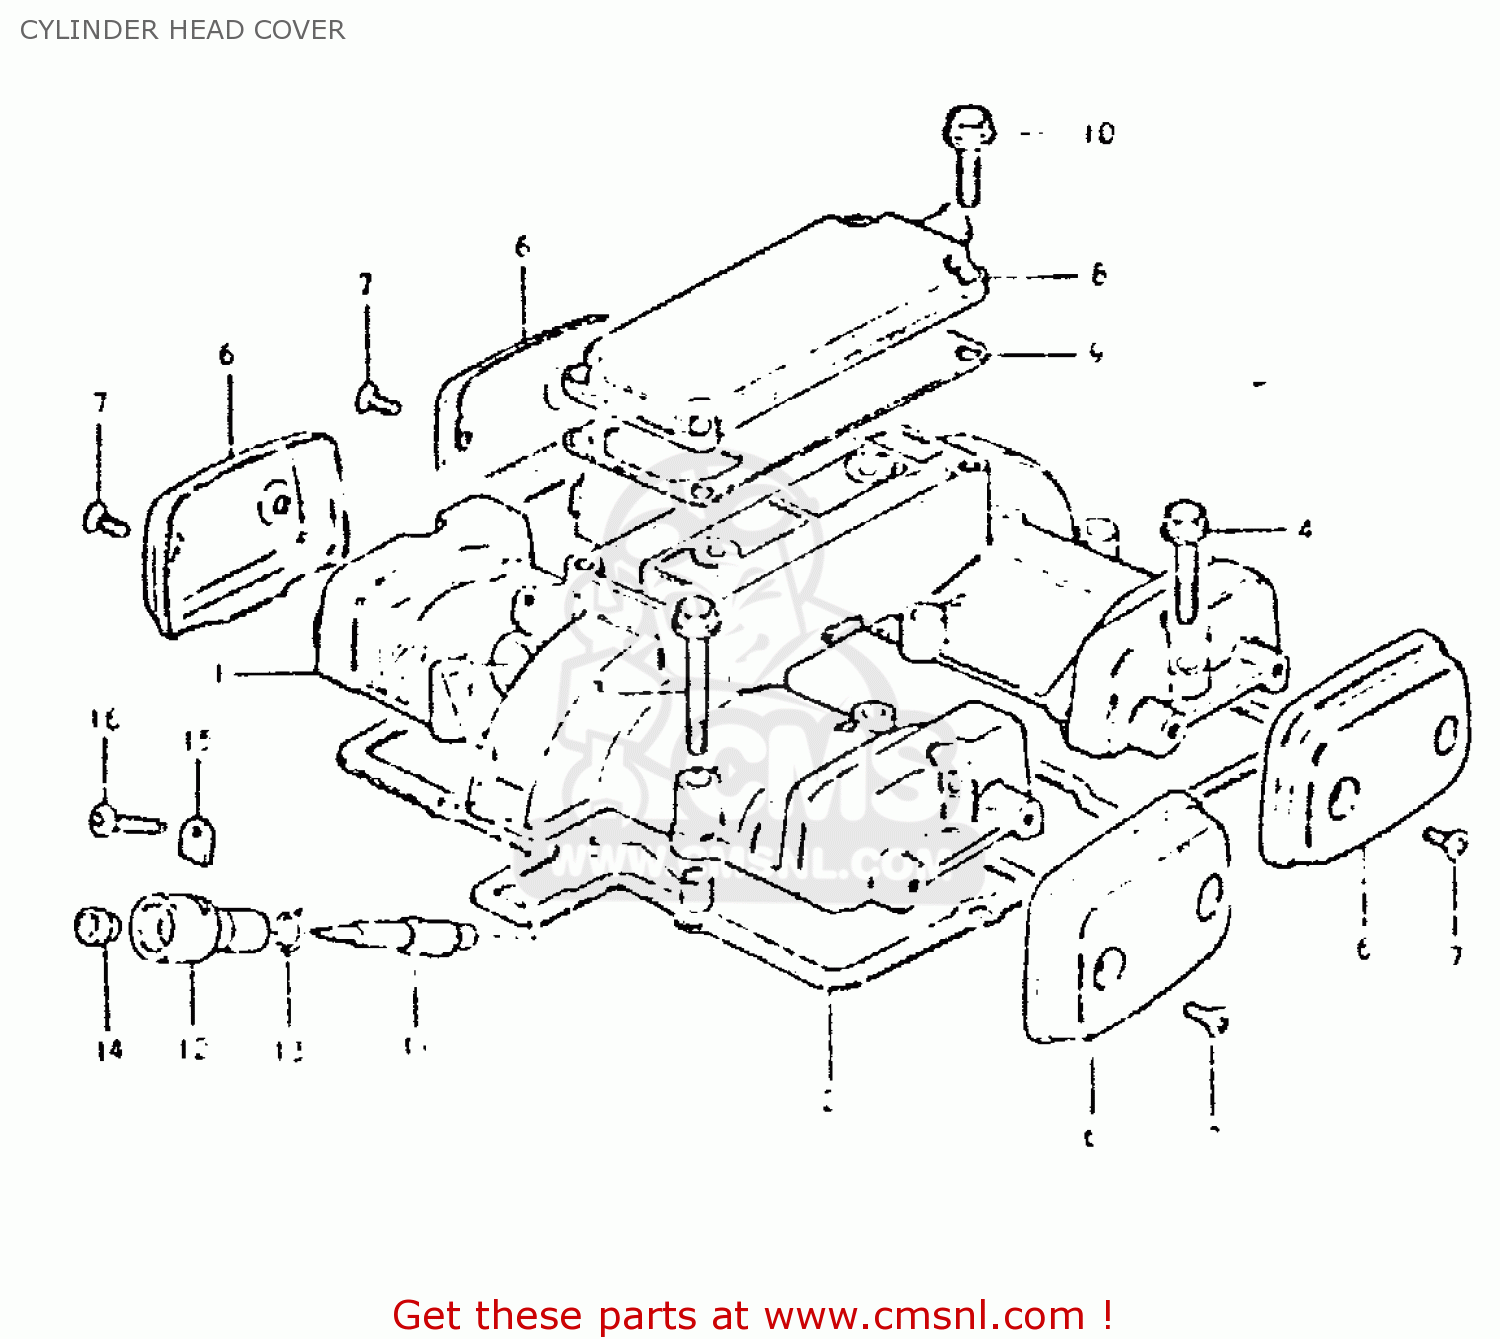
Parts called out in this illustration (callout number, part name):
1	COVER, CYLINDER HEAD
2	GASKET (MCA)
3	BOLT 6X35
4	BOLT
5	PIN(6.2X8X11)
6	CAP,CYLINDER HEAD COVER
7	SCREW 5X12
8	COVER,BREATHER
9	GASKET (MCA)
10	BOLT,REAR
11	GEAR,TACHOMETER DRIVEN
12	SLEEVE,TACHOMETER DRIVE
13	SEAL,TACHOMETER DRIVEN
14	SEAL,OIL(5X12X8)
15	PLATE,TACH DRIVE GEAR SLEEVE
16	SCREW(5X12)
